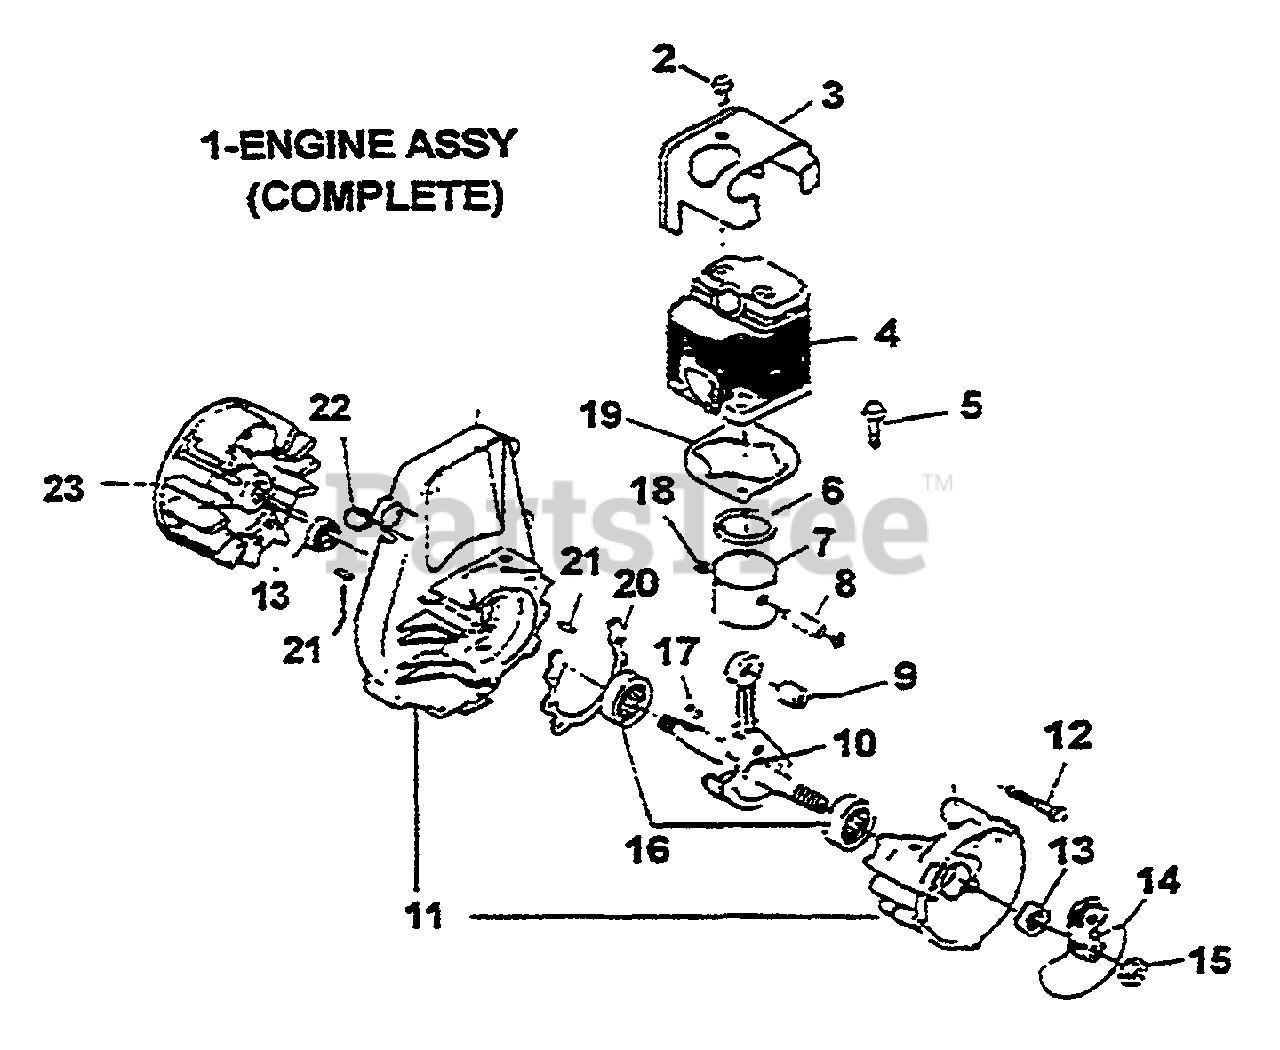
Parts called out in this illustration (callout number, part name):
1	ENGINE ASSY
3	COVER, CYLINDER
4	CYLINDER
6	RING, PISTON
7	PISTON
8	WRIST PIN
10	CRANKSHAFT ASSY
11	CRANKCASE ASSY
14	RATCHET ASSY
17	KEY, FLYWHEEL
18	SNAP RING
19	GASKET, CYLINDER
20	GASKET, CRANKCASE
23	FLY WHEEL
